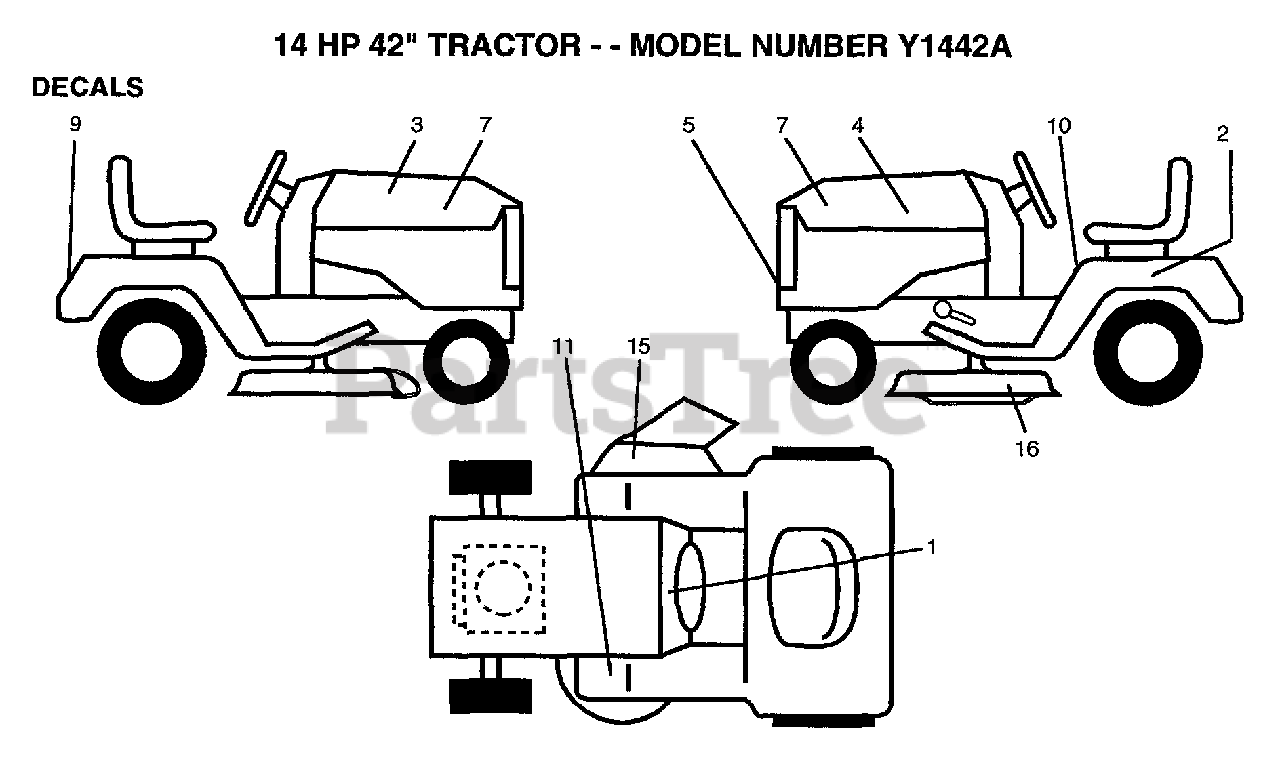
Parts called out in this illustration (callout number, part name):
2	DECAL
10	DECAL
11	DECAL T
15	DECAL WARNING
16	DECAL YT
